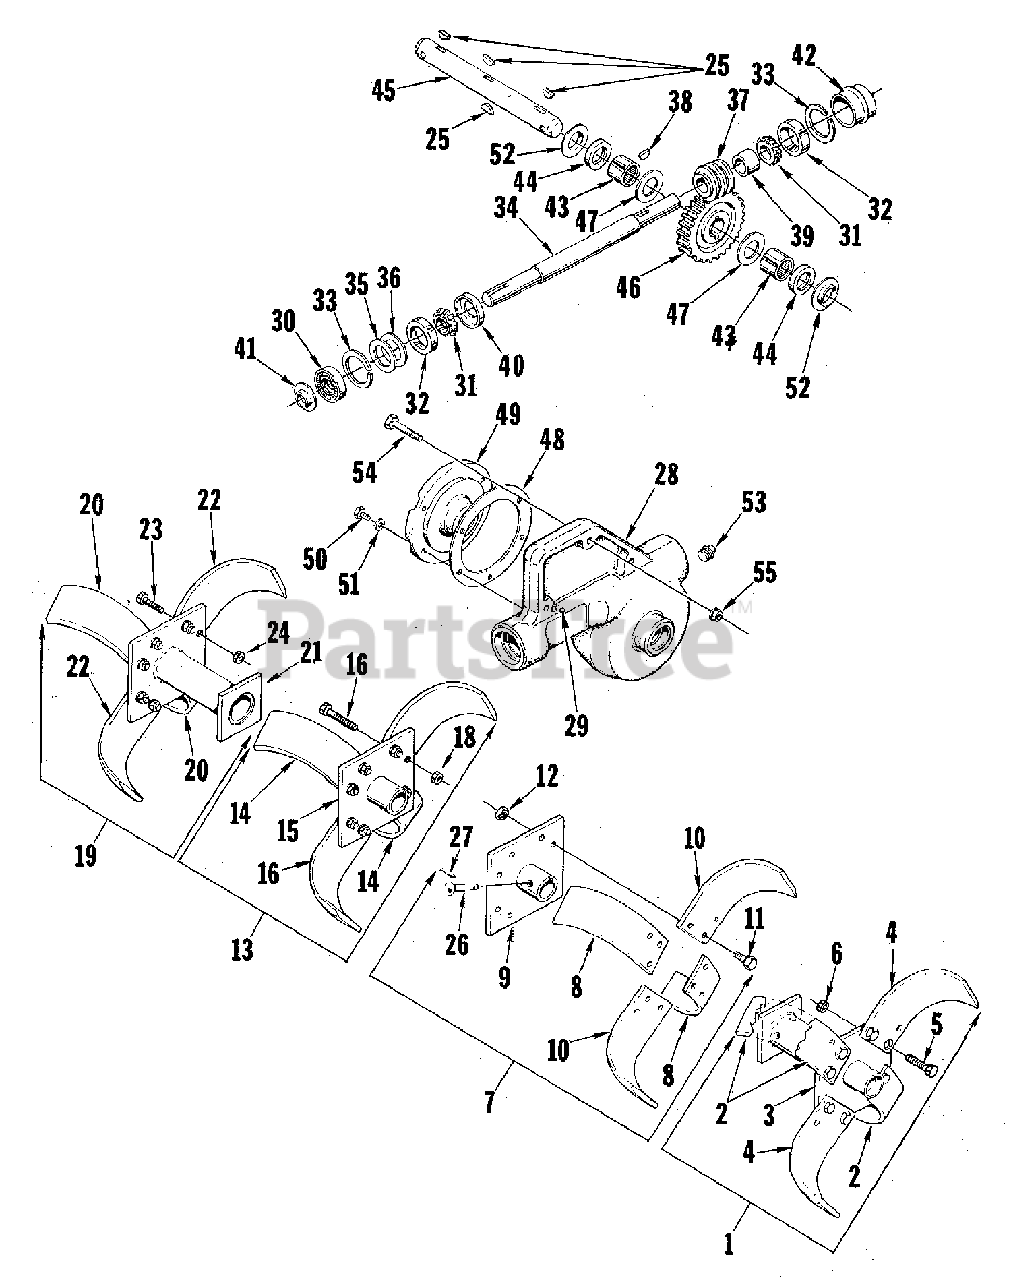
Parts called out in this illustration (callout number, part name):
1	BLADE ASSEMBLY, Tine, Outer, (R.H.)
2	BLADE, Tine (L.H.)
3	PLATE, Tine, Outer
4	BLADE, Tine (R.H.)
5	SCREW, Hex, Cap, 3/8-16 x 1"
6	NUT, Hex, 3/8-16
7	BLADE ASSEMBLY, Tine, Inner (R.H.)
8	BLADE, Tine (L.H.)
9	PLATE, Tine, Outer
10	BLADE, Tine (R.H.)
11	SCREW, Hex, Cap, 3/8-16 x 1"
12	NUT, Hex, 3/8-16
13	BLADE ASSEMBLY, Tine, Outer, (L.H.)
14	BLADE, Tine (L.H.)
15	PLATE, Tine, Outer
16	BLADE, Tine (R.H.)
17	SCREW, Hex, Cap, 3/8-16 x 1"
18	NUT, Hex, 3/8-16
19	BLADE ASSEMBLY, Tine, Outer, (L.H.)
20	BLADE, Tine (L.H.)
21	PLATE, Tine, Outer
22	BLADE, Tine (R.H.)
23	SCREW, Hex, Cap, 3/8-16 x 1"
24	NUT, Hex, 3/8-16
25	KEY, Woodruff, #91
28	HOUSING, Worm Drive
31	BEARING, Roller
32	BEARING, Cup
35	RING, Backing
36	RING, Backing
37	WORM, Right Hand
38	KEY, Hi-Pro, 3/16 x 7/8
43	BEARING, Needle
45	SHAFT, Worm Gear
46	GEAR, Worm (R.H.)
47	WASHER, Thrust
50	SCREW, Hex Cap, 1/4-20 x 5/8
51	WASHER, Lock, 1/4"
53	PLUG, Pipe, 3/8"
54	SCREW, Hex Cap, 3/8-24 x 1-3/4"
